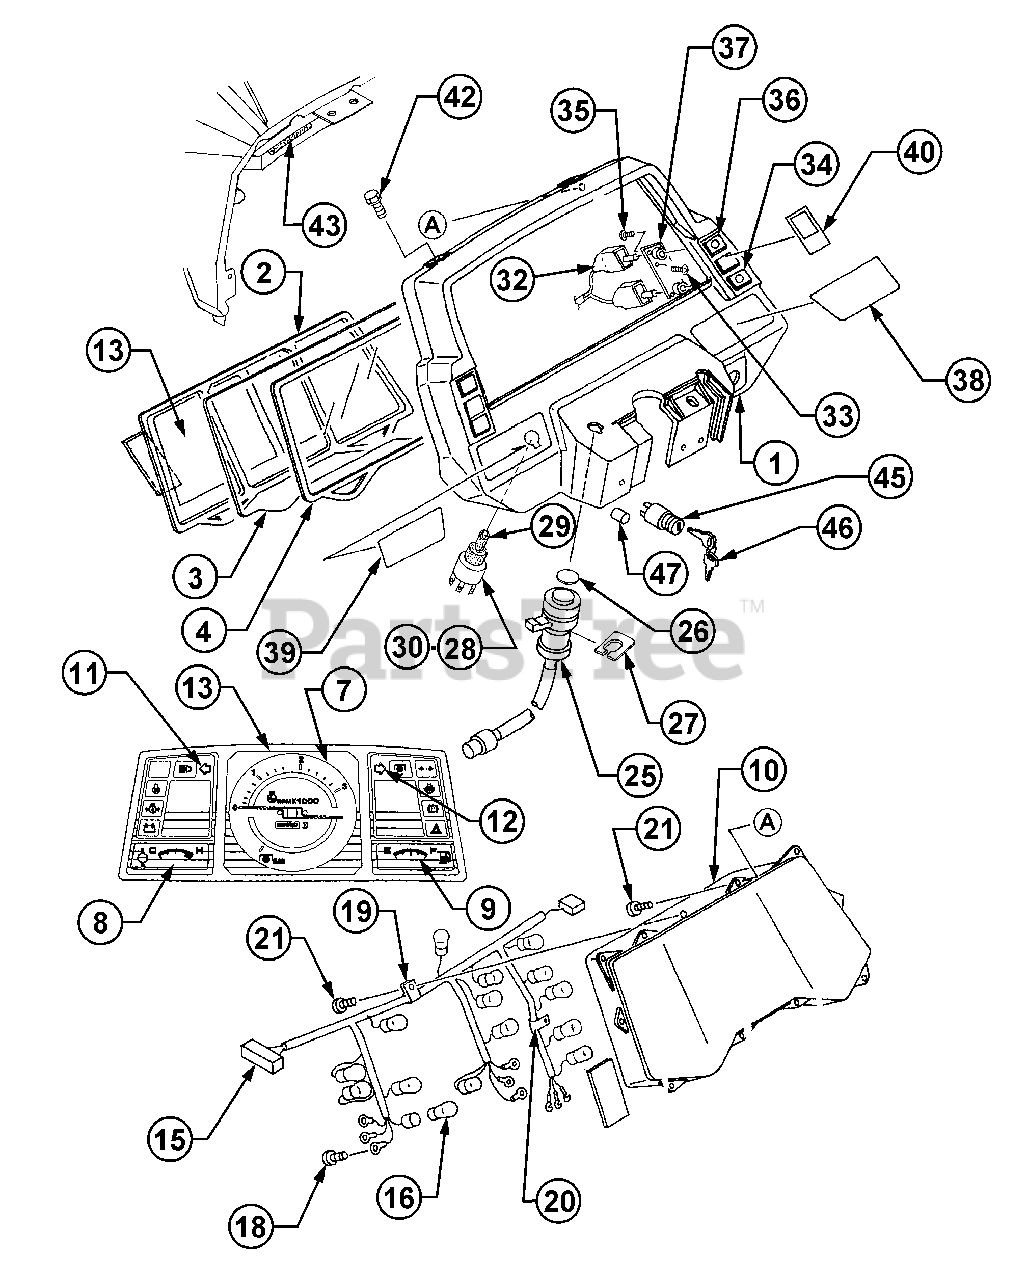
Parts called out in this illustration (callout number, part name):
10	Case
13	Meter, Design
15	Harness
18	Screw, w/Washer
19	Clamp
20	Clamp
25	Switch Assy
28	Switch, Light
35	Screw, Tapping
45	Switch, Starter
46	Key, Group
